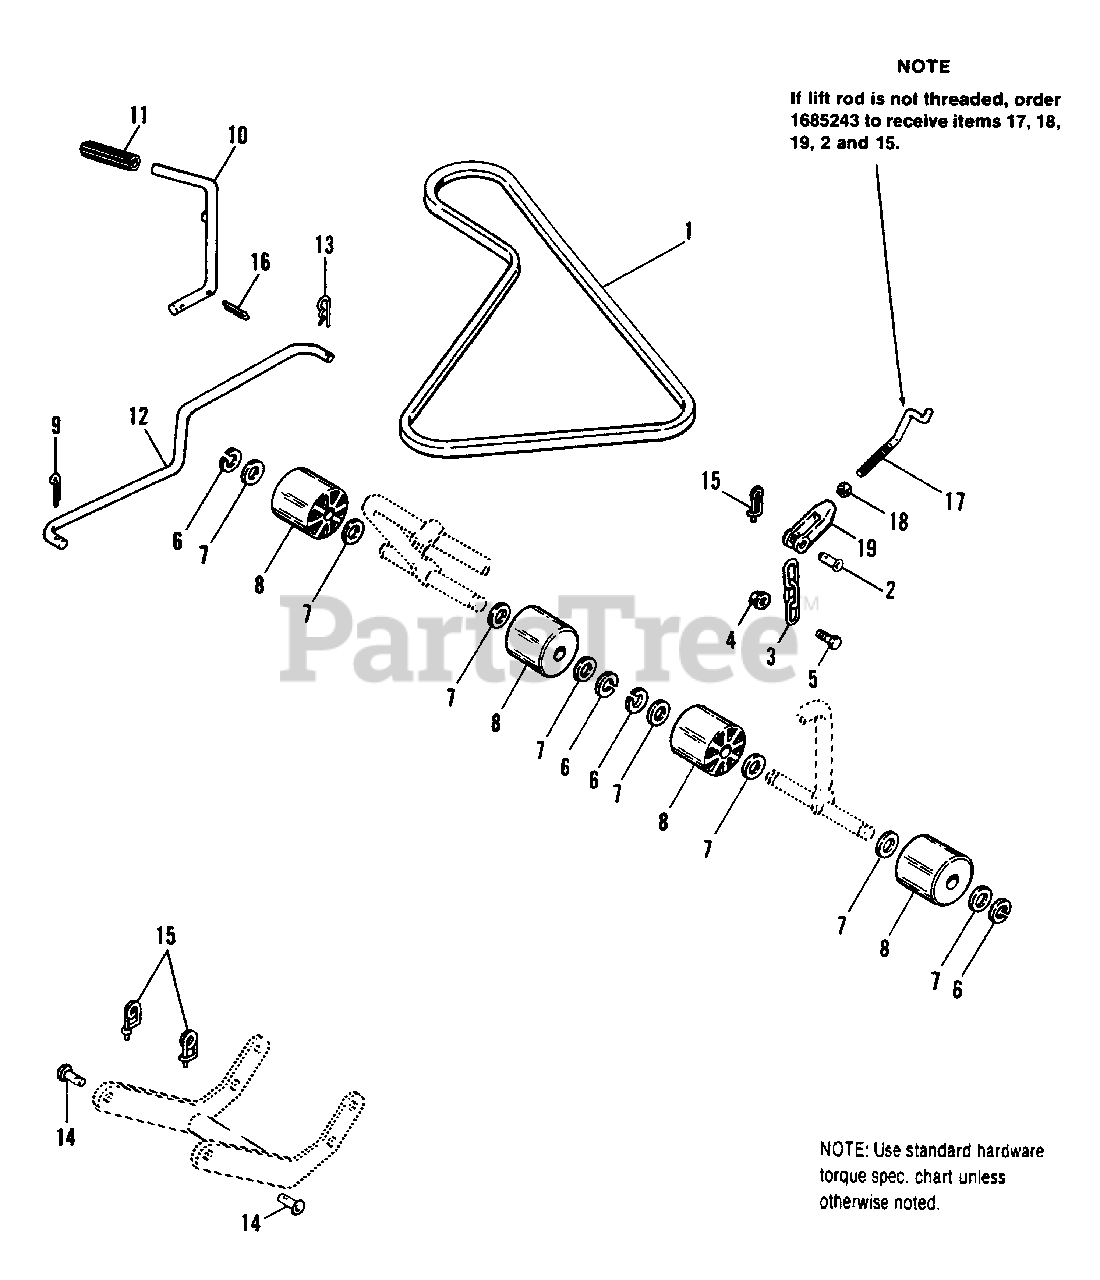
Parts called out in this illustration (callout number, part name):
1	V-BELT, Mower Drive
2	PIN, Rivet
3	CHAIN, Lift
4	LOCKNUT, Hex, Flange, 5/16-18
5	CAPSCREW, Hex Hd., 5/16-18 x 1
6	RING, Retaining
7	WASHER, Plain, 5/8
9	PIN, Cotter, 3/32 x 1
10	LEVER, Control
11	GRIP, Handle
12	ROD, P.T.O.
13	CLIP, Spring
15	CLIP, Pin, Safety
16	PIN, Cotter, 1/8 x 1
18	NUT, Jam, 5/16-18
